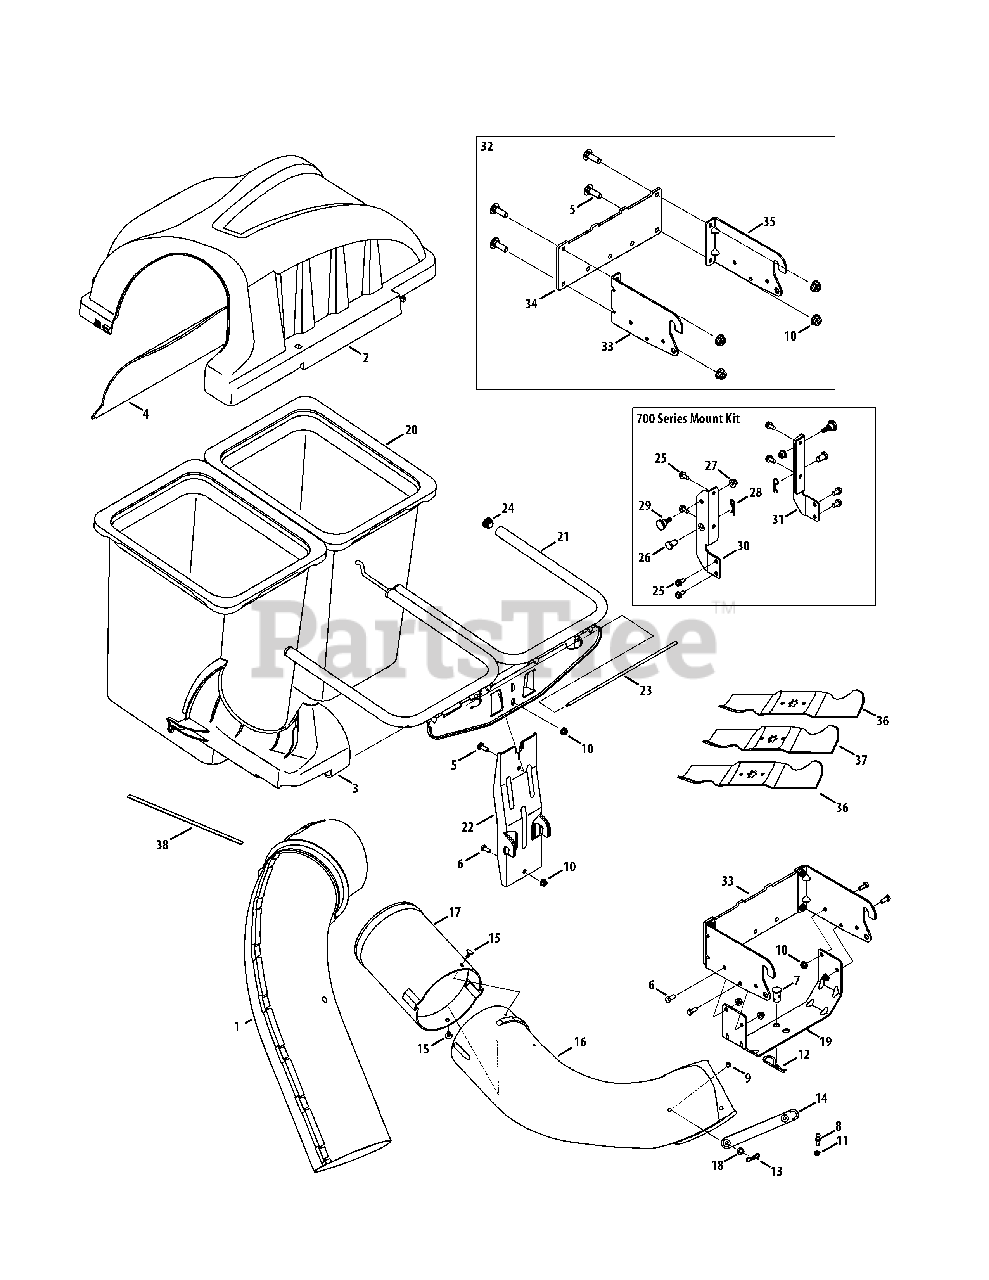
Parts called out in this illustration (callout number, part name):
1	Upper Chute Assembly
2	Double Bagger Cover Assembly
3	Upper Chute Support
4	Bagger Cover Screen
5	Carriage Screw, 5/16-18 x 1.00"
6	Hex Head Screw, 5/16-18 x .75"
7	Clevis Pin, .62" Dia.
8	Grass-catcher Pin, 1/4-20
9	Clevis Pin, 5/16 x .75 Lg.
10	Flange Lock Nut, 5/16-18
11	Flange Lock Nut, 1/4-20
12	Internal Cotter Pin, .148 x 3.00
13	Bow-Tie Cotter Pin, 72
14	Chute Strap, 6.00 Lg.
15	Ratchet Clip, .250
16	Discharge Chute Elbow, 46" Deck
17	Bagger Chute Adapter, 7 In.
18	Flat Washer, .344 x .62 x .033
19	Universal Bracket Support, RT-99/LT-5
20	Grass-bag Assembly
23	Cover Hinge Pin
24	End Plug
25	Tap Screw, 5/16-18 x .750
26	Clevis Pin, .50 x .78 Lg.
27	Flange Lock Nut, 3/8-16
28	Click Pin, .092 x 1.64 Lg.
29	Shoulder Screw, .625 x .412
32	Hitch Bracket Assembly
33	Hitch Bracket, RH
34	Universal Rear Attachment Bracket
35	Hitch Bracket, LH
36	Blade, 16.28 Lg., Star 2-in-1
37	Blade, 14.88 Lg., Star 2-in-1
38	Self-Adhesive Foam Strip
